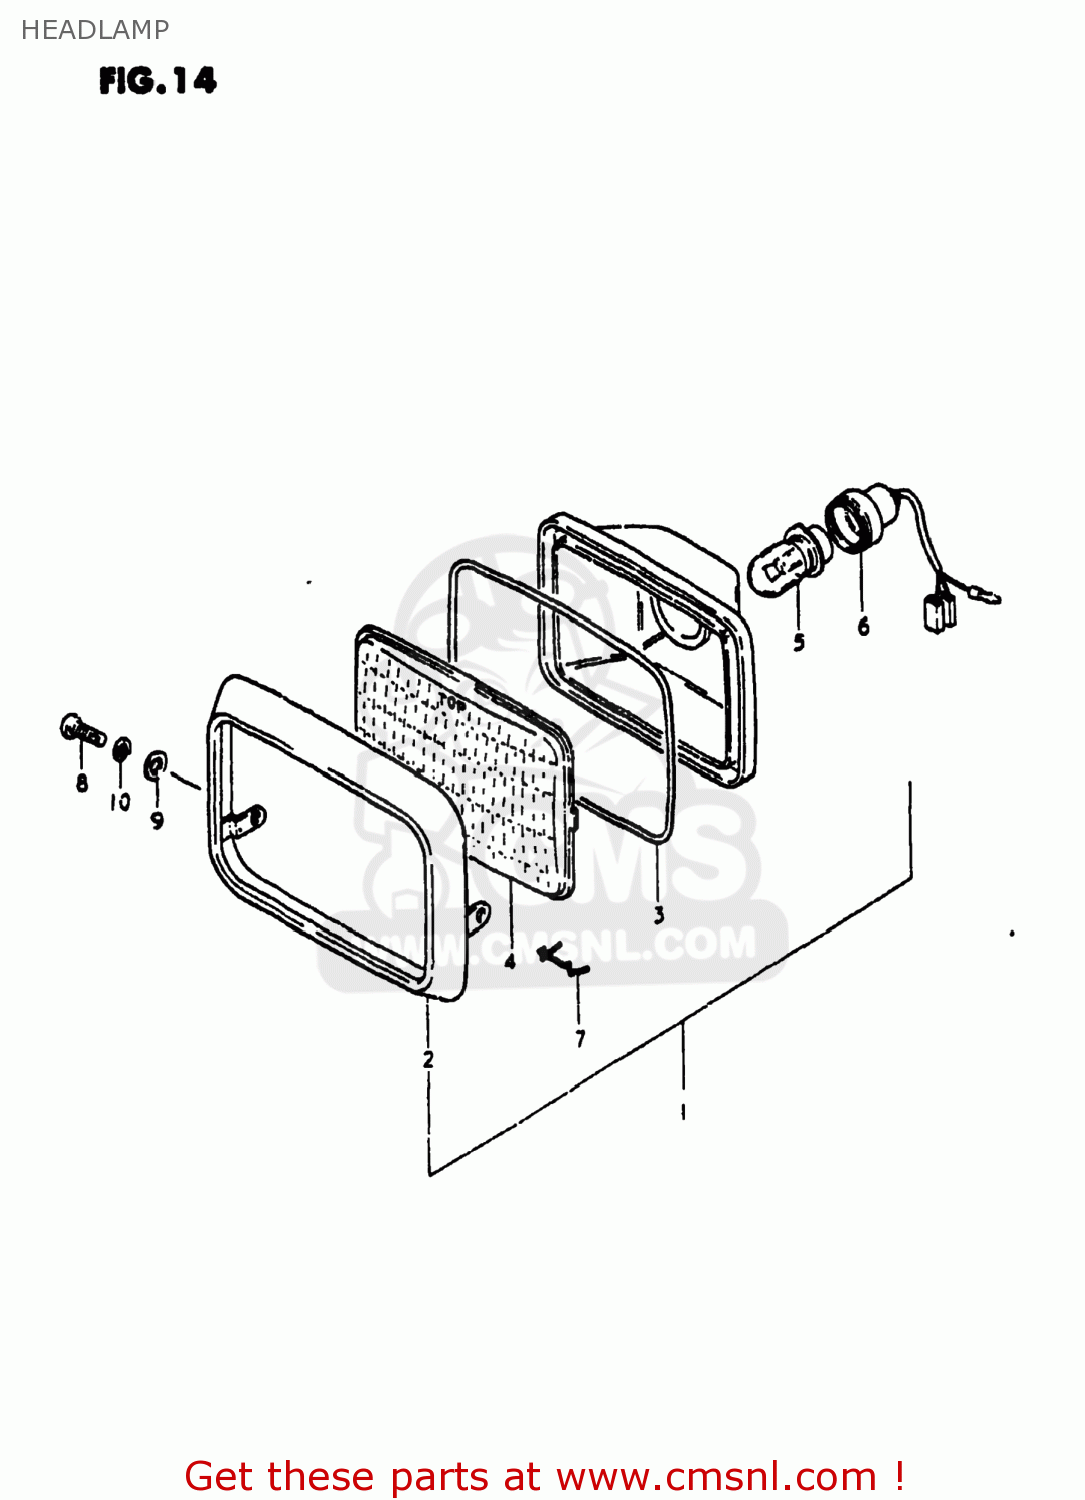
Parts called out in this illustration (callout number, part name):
1	LAMP ASSEMBLY,HEAD
2	RIM,HEADLAMP
3	GASKET,HEADLAMP LENS (NAS)
4	LENS,HEADLAMP (PLASTIC)
5	BULB(6V15/15W/STANLEY,A3598HA)
6	SOCKET,BULB
7	SPRING,HEADLAMP UNIT
8	SCREW
9	LOCK WASHER
10	WASHER
